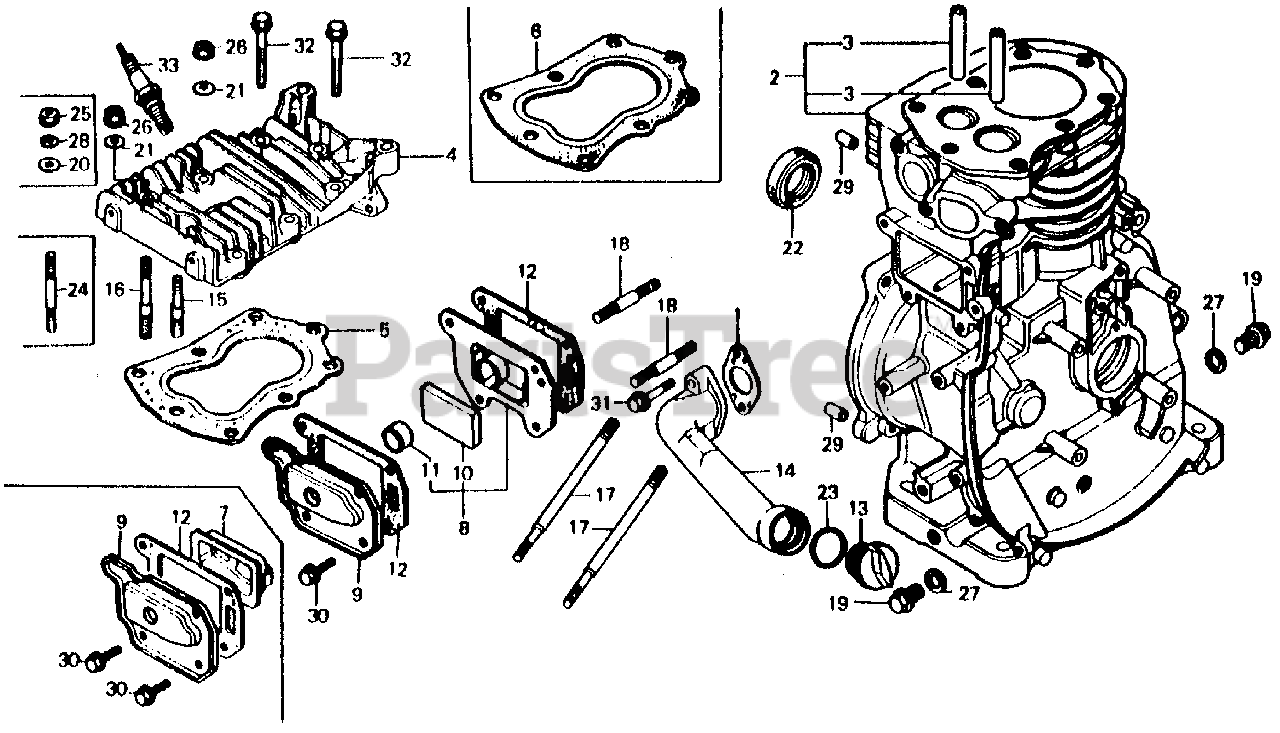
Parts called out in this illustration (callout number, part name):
1	GASKET, OIL PAN
2	CYLINDER (CRANKSHAFT P.T.O.)
2	CYLINDER
3	GUIDE, VALVE
4	CYLINDER HEAD
5	GASKET, CYLINDER HEAD
6	GASKET, CYLINDER HEAD Use from Engine SN 1103183.
7	CASE, BREATHER
8	CASE, BREATHER
9	COVER, TAPPET
10	FILTER, BREATHER
11	SEAL, BREATHER
12	GASKET, TAPPET COVER
15	BOLT, STUD (M8XM10X63)
16	BOLT, STUD (M8XM10X81)
17	BOLT, STUD (8X110)
17	BOLT, STUD (8X104)
18	BOLT, STUD (8X35)
19	BOLT, DRAIN PLUG
20	WASHER, HEAD (8MM)
21	WASHER (8MM)
22	OIL SEAL (25X41X6)
23	O-RING (26X2.7)
24	BOLT, STUD (8X65)
24	BOLT, STUD (8X80) (NOT AVAILABLE)
25	NUT, FLANGE (8MM)
26	NUT-WASHER (8MM)
27	WASHER, DRAIN PLUG (12MM)
28	WASHER, SPRING (8MM)
29	PIN A, DOWEL (8X14)
30	BOLT, FLANGE (6X12)
31	BOLT, FLANGE (6X25)
32	BOLT, FLANGE (8X50) (NOT AVAILABLE)
33	SPARK PLUG (BR-4HS) (NGK)
33	SPARK PLUG (W14FR-U) (DENSO)
